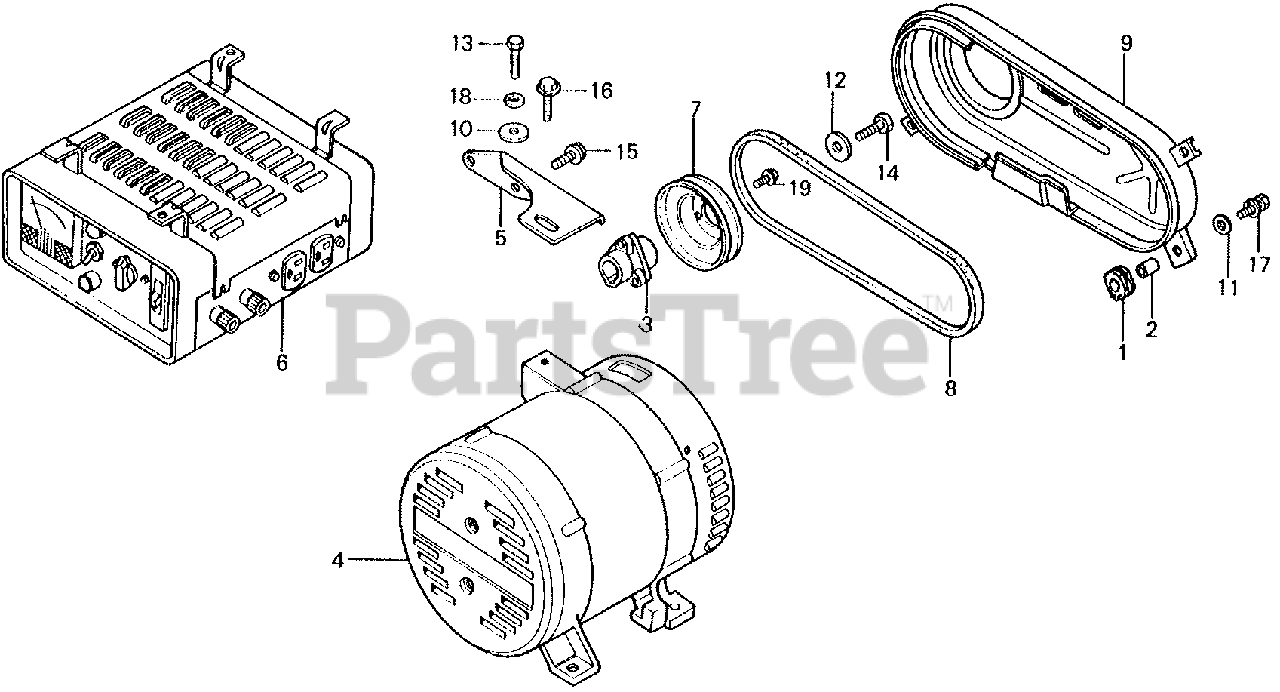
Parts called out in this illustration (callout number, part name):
1	RUBBER, TANK CUSHION (NOT AVAILABLE)
2	COLLAR, DISTANCE
3	BOSS, DRIVE PULLEY (NOT AVAILABLE)
4	ALTERNATOR ASSY. *R8/NH31/NH1* (BRIGHT RED/MC KINLEY WHITE/ BLACK)
5	STAY, ALTERNATOR (NOT AVAILABLE)
6	BOX ASSY., CONTROL *R8* (BRIGHT RED)
7	PULLEY, DRIVE (50HZ) (NOT AVAILABLE)
8	V-BELT (SB-30)
9	COVER, BELT *R8* (BRIGHT RED)
10	WASHER (8MM)
11	WASHER, FLAT (20MM)
12	WASHER, LOCK (8MM)
13	BOLT, HEX. (8X22)
14	BOLT, HEX. (8X25)
15	BOLT-WASHER (8X16)
16	BOLT-WASHER (8X20)
17	BOLT-WASHER (6X20)
18	WASHER, SPRING (8MM)
19	BOLT, FLANGE (6X16)
